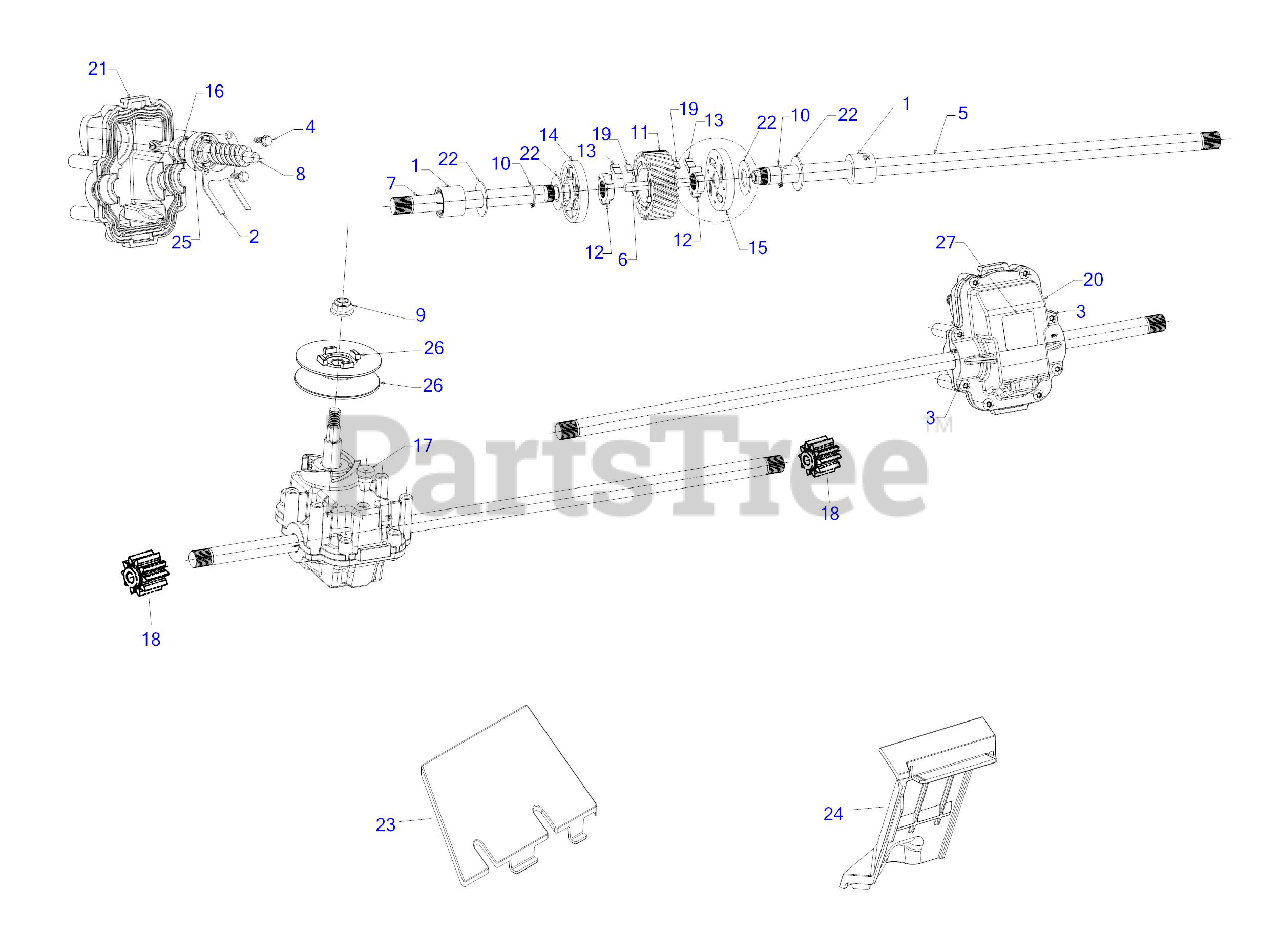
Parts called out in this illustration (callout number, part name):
1	#N/A
2	#N/A
3	SCREW .159 x .610
4	SCREW .159 x .43
5	#N/A
6	#N/A
7	#N/A
8	#N/A
9	FLANGE LOCK NUT 5/16-18
10	SNAP RING FOR .500
11	#N/A
12	#N/A
13	#N/A
14	#N/A
15	#N/A
17	RUBBER PLUG
18	SPUR GEAR 9T
19	#N/A
20	#N/A
21	#N/A
22	FLAT WASHER .508X1.000X.040
23	TRANSMISSION COVER (REAR)
24	TRANSMISSION COVER (FRONT)
25	BALL BEARING
26	HALF PULLEY 2.5 OD
27	LABEL
